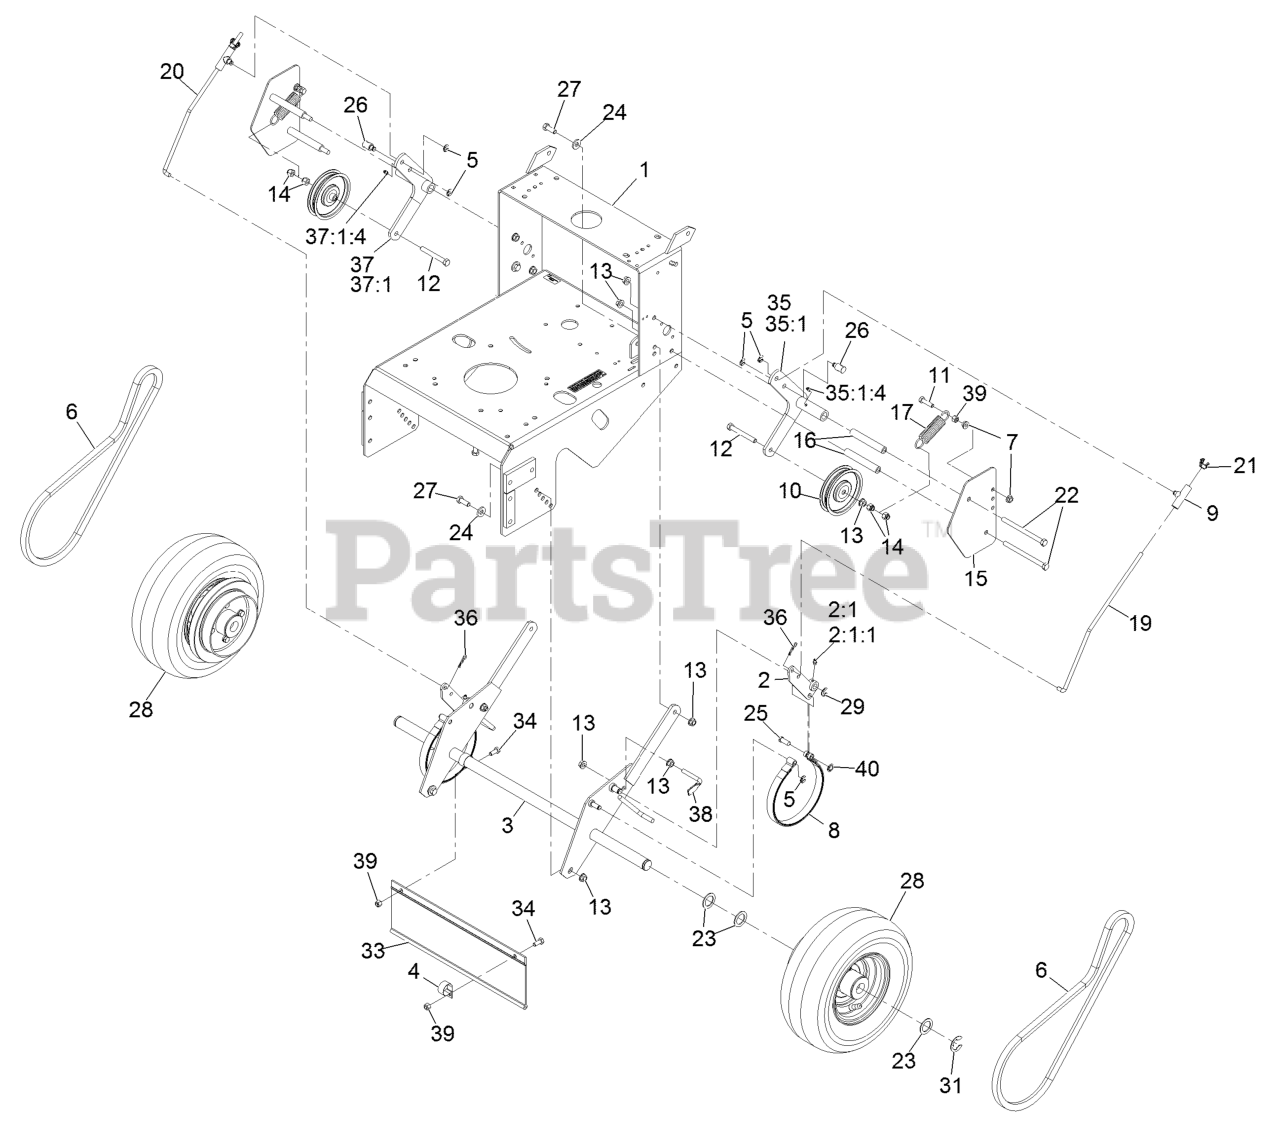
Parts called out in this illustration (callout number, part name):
1	ASM, METRO ENGINE DECK W/
2	ARM-BRAKE
2:1	Wld,Brake Arm
2:1:1	ASM,BUSHING/ZERK
4	CLAMP-R
5	RING-RETAINING
6	BELT,WHEEL DRIVE
8	BAND-BRAKE
9	SWIVEL-BRAKE
10	IDLER-WHEEL, DRIVE
11	SCREW-HH, SPECIAL
12	SCREW-HH
13	NUT-HHF, WHIZ
14	NUT-LOCK, NI
15	SHIELD-WHEEL, DRIVE
16	SPACER-SHIELD
17	SPRING-EXTENSION
19	LINKAGE-BRAKE, LH
20	LINKAGE-BRAKE, RH
21	WINGNUT-NYLOCK
22	SCREW-HH
23	WASHER-SPACER
24	WASHER-BELLEVILLE
25	PIN-CLEVIS
26	SWIVEL-DRIVE LEVER, 3/8 L
27	SCREW-HH
28	DRIVE WHEEL ASM
29	RING-RETAINING, EXTERNAL
31	RING-SNAP
33	SHIELD-TRAILING
34	SCREW-HH
35	ARM-IDLER, LH
35:1	Idler Arm LH Assy
35:1:4	FITTING-GREASE
36	PIN-COTTER
37	ARM-IDLER, RH
37:1	Idler Arm RH Assy
37:1:4	FITTING-GREASE
38	SCRAPER
39	NUT-LOCK, NI
40	RING-RETAIN,PUSH,EXT,FLAT
